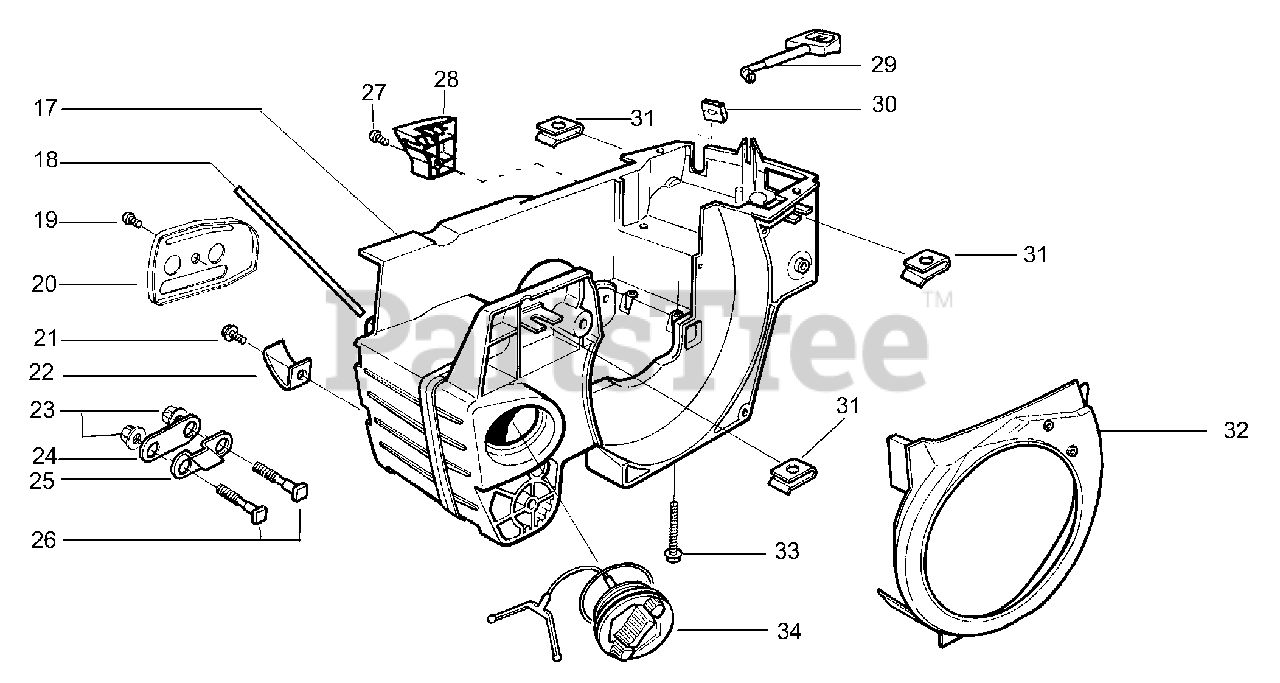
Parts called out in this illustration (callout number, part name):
17	Kit - Chassis Ass'y.
18	Tube-Oil Vent
19	Screw
22	Chain Catcher
25	Bar Stud Plate
29	Choke Lever
31	Type "U" Speed Nut
32	Baffle Plate
34	Assy.- Oil Tank Cap
